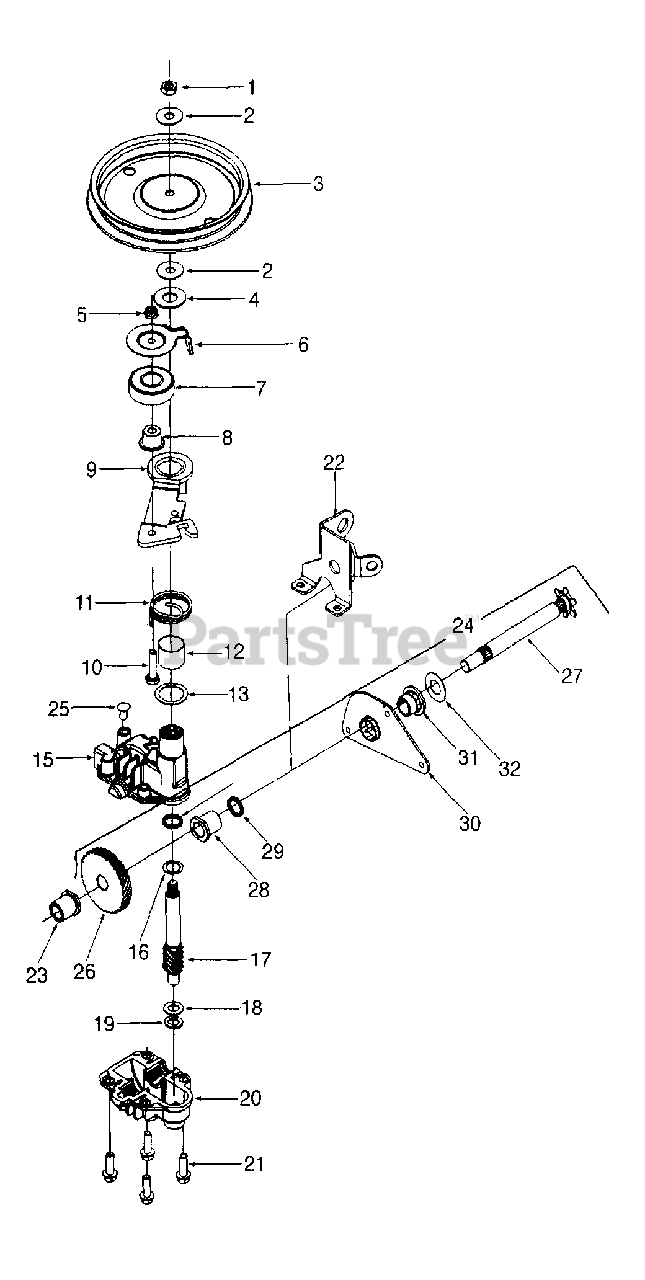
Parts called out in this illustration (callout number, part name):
1	Hex Jam Nut 5/16 - 24
2	Bell Washer.325 x .930 x .045
3	Pulley
4	Flat Washer .510 x 1.10 x .060
5	Hex Lock Nut 1/4 - 28
6	Belt Keeper
7	Bearing
8	Flange Spacer
9	Idler Bracket Assembly
10	Hex. Cap Scr. 1/4-28 x 1.00 Gr. 5
11	Torsion Spring
12	Bearing Sleeve
13	Flat Washer .855 x 1.250 x .030
15	Upper Housing Assembly
16	Flat Washer .504 x .700 x .030
17	Pinion Shaft 10T
18	Thrust Washer .382 I.D. x .684 O.D.
19	Thrust Washer .388 x .625 x .062
20	Lower Housing Ass'y,
21	Hex Scr. TT 1/4-20 x .75
24	Shaft Assembly.
26	Gear 347.
27	Output Shaft 6T.
28	Flange Bearing
29	Oil Seal
30	Pivot Bracket
31	Flange Bearing
32	Fl. Wash. .508 I.D. x 1 O.D. x .020
